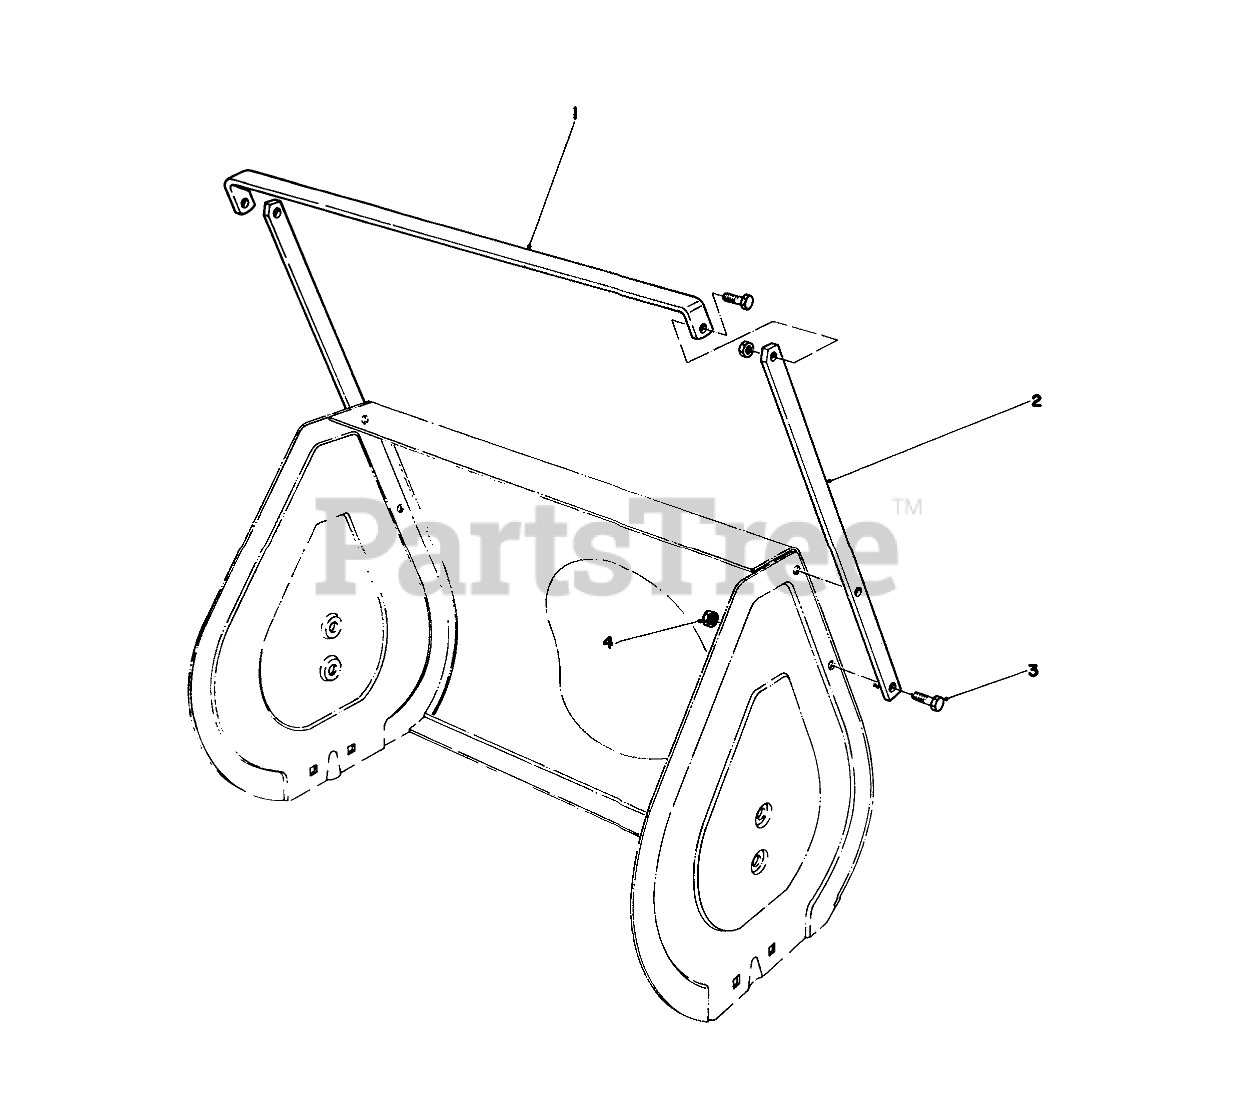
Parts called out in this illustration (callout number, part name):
1	Drift Breaker-Top
2	Drift Breaker-Side
3	SCREW-HH
4	NUT-LOCK, NI
